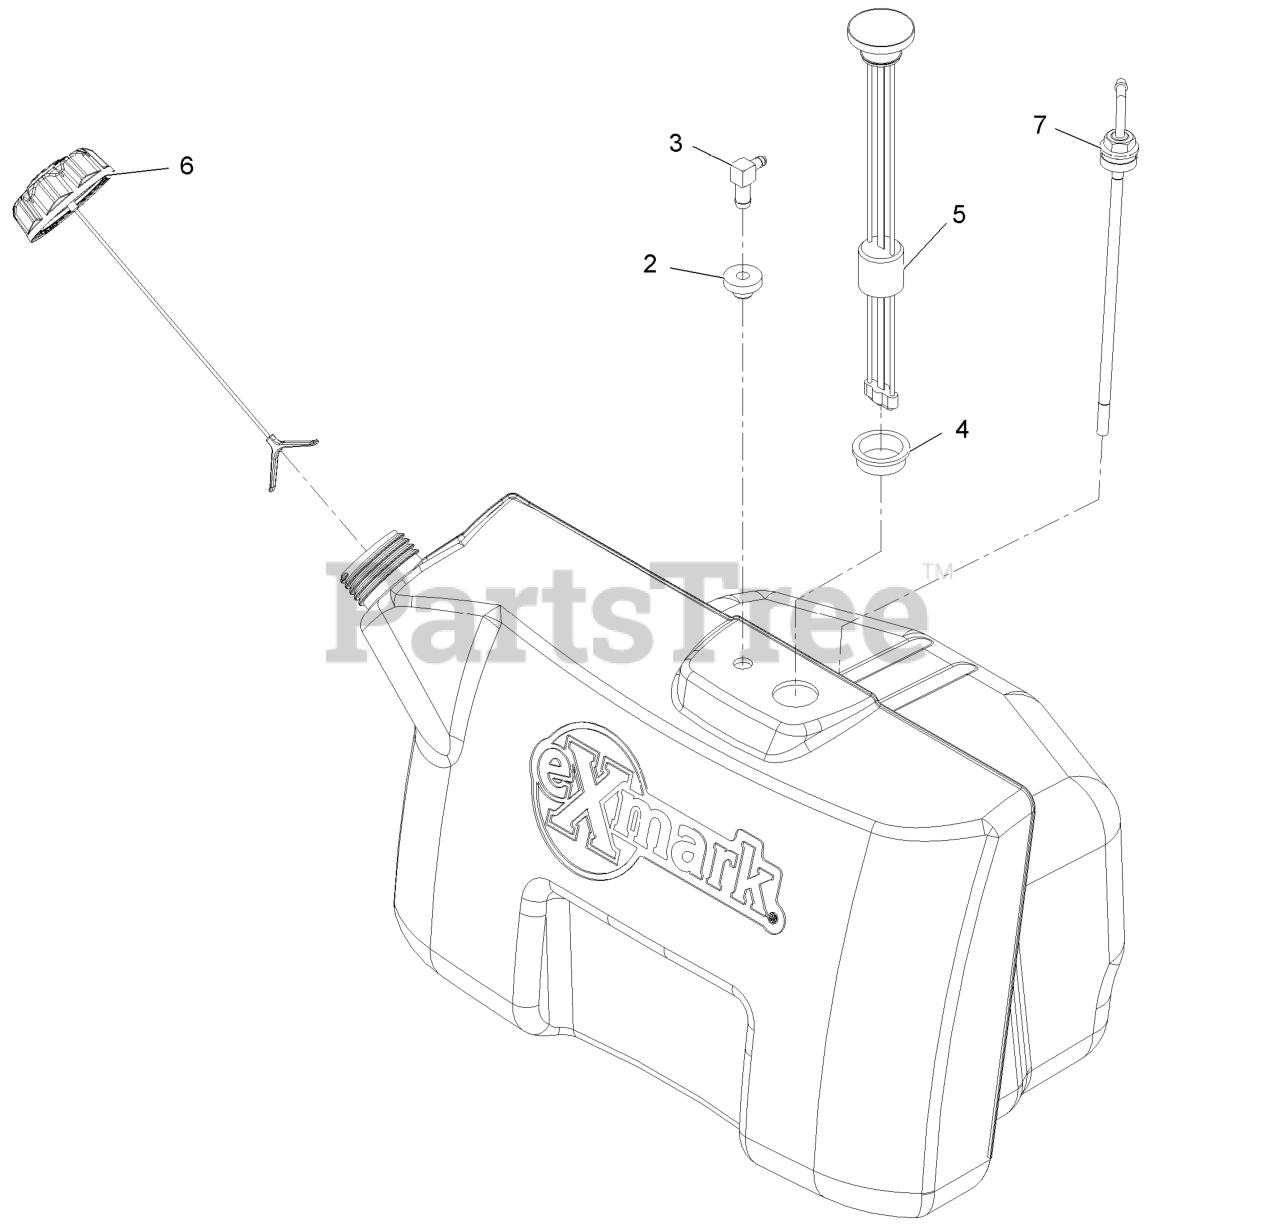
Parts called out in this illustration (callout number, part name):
2	BUSHING
3	ELBOW-90 DEG
4	CONTACT ORDER SERVICES
7	FITTING-FUEL, BULKHEAD
